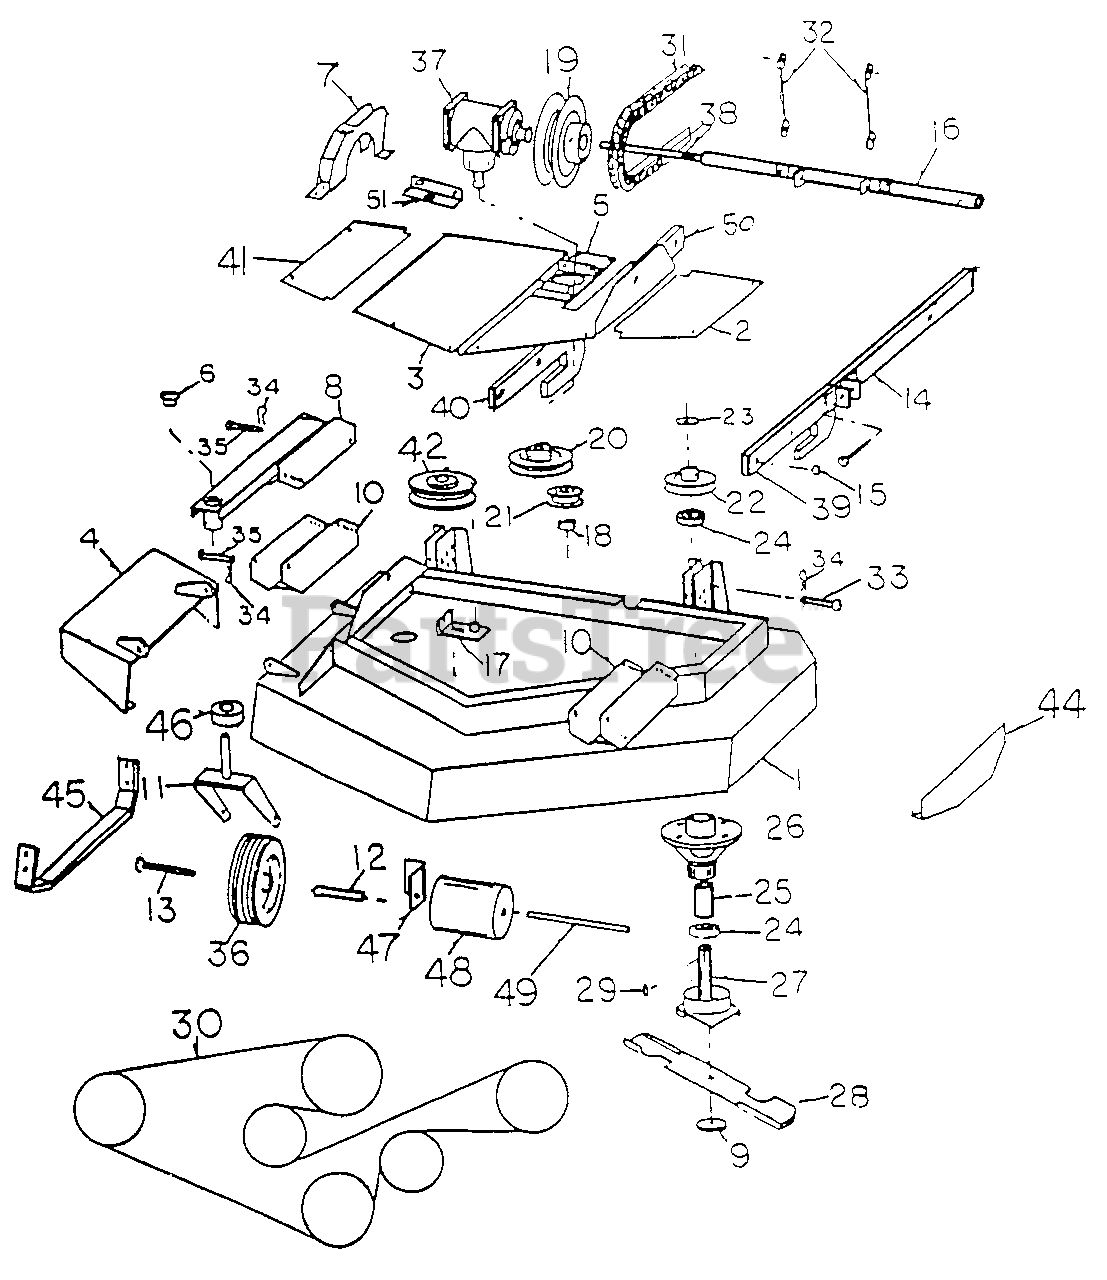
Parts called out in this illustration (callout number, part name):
1	Mower Deck
2	Cover
3	Cover
5	Gear Box Mount
6	Gauge Wheel Bearings
8	Gage Wheel Mount
10	Bracket, Gage Wheel Mount
11	Fork Gage Wheel
12	Axle
13	Axle Bolt
14	LHI Deck Lift Arm Back Adjustable
15	Bushing, Deck Lift Arm
17	Belt Tightener
18	Spacer Idler
19	Pulley Gear Box
20	Pulley Gear Box
21	5" Idler
22	Pulley Spindle
23	Washer Spindle
24	Bearing, Spindle
25	Spacer Spindle
26	Housing Spindle
27	Shaft Spindle
29	Key Spindle
35	Pins, Gage Wheel
38	Cross Bar Pin
39	L.H.1 Deck Lift Arm Front Adjustable L.H.
40	R.H.1 Deck Lift Arm Front Adjustable R.H.
41	Cover, Right Hand Side
42	Pulley, Idler Large
44	Shoe Left Hand Side
45	Shoe Right Hande Side
47	Rollar Bracket
50	R.H.1 Deck Lift Arm, Back Adjustable
51	Gear Box Mount Angle
